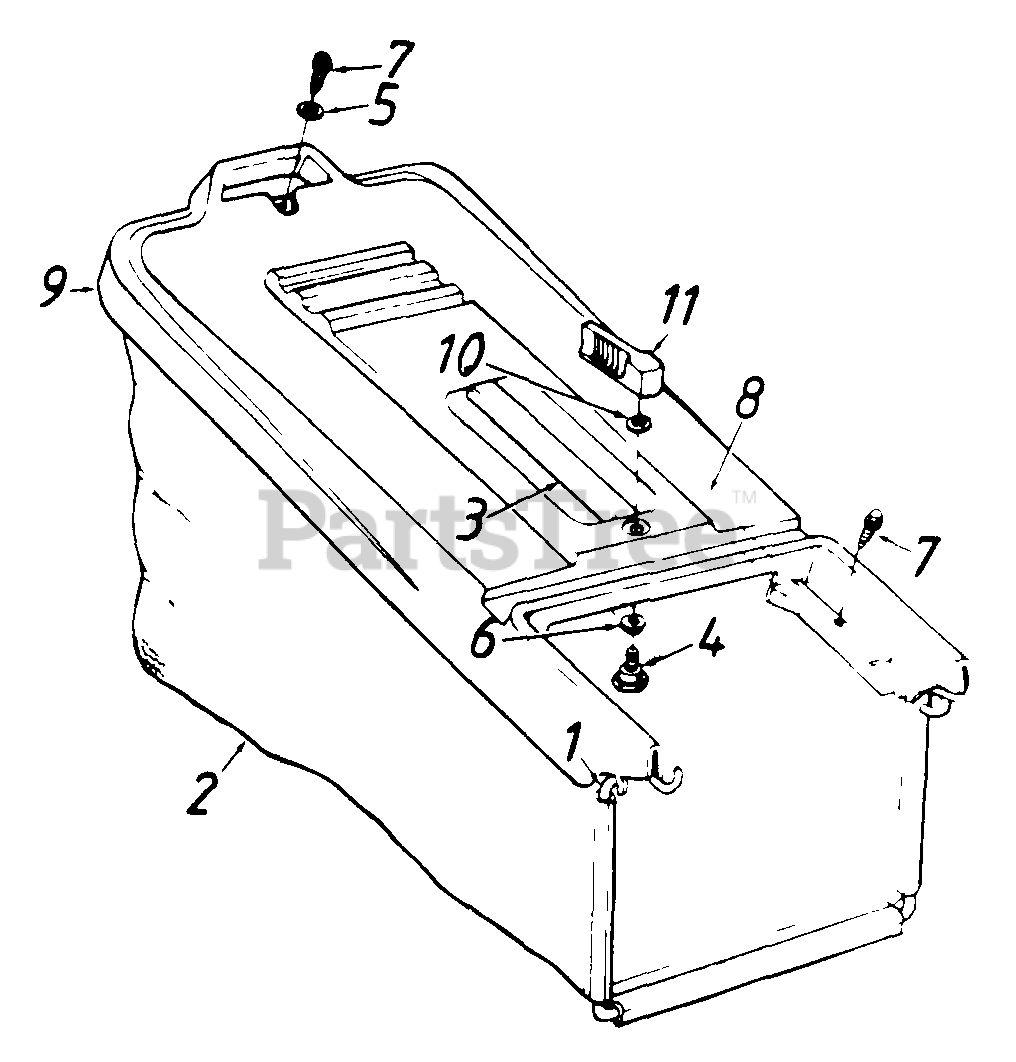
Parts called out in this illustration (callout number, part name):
2	Grass Bag
3	Hardtop Handle
4	Shoulder Bolt
5	Fl-Wash. 281" I.D.
6	Bowed Washer
7	Hex L-Wash AB-Tap Scr 1/4 x .62"
10	Internal L-Wash. 1/4" I.D.
11	Locking Knob
